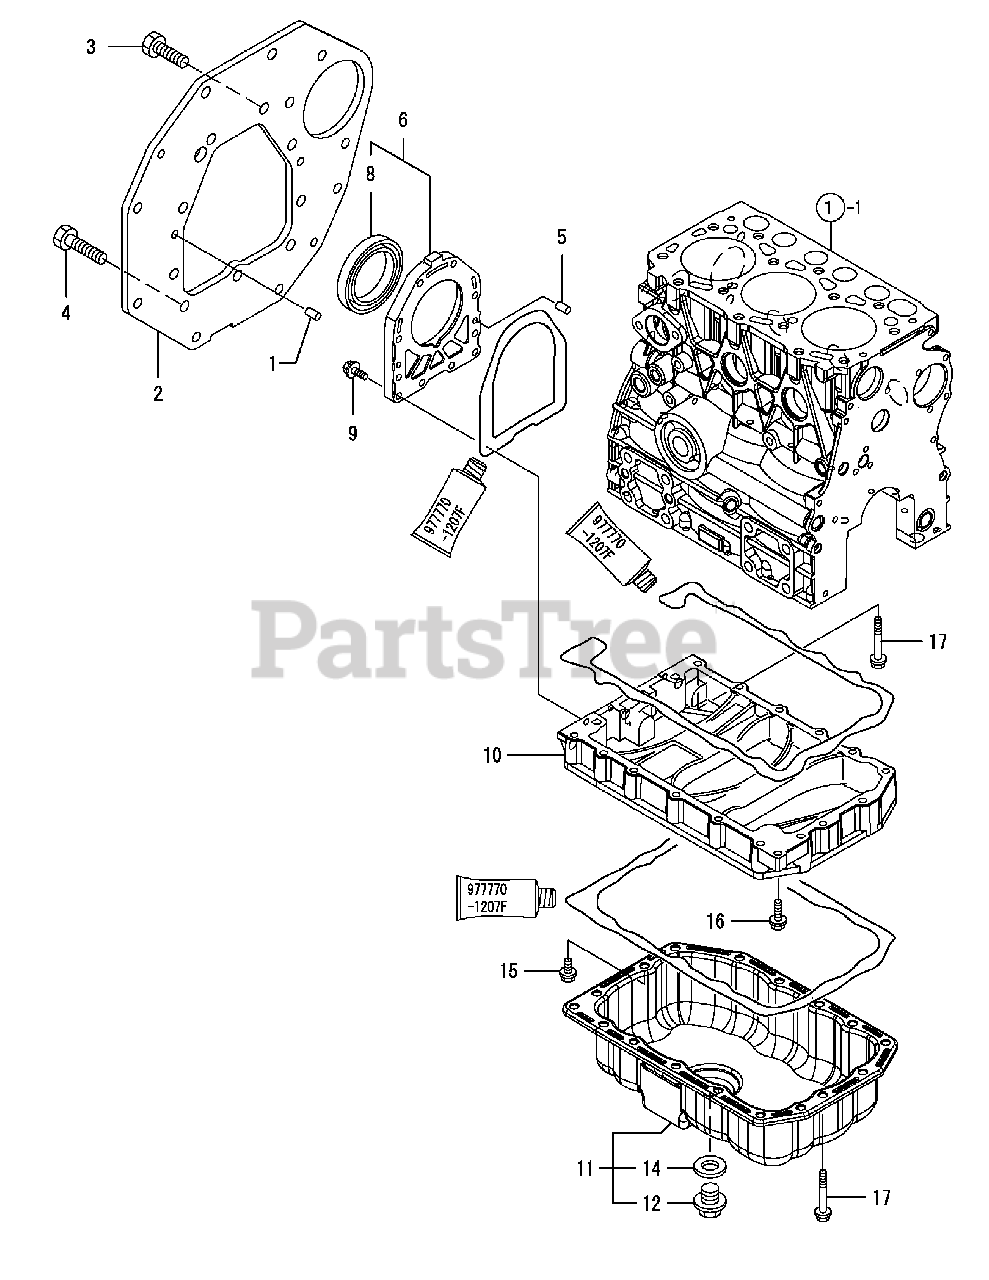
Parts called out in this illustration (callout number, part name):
1	Parallel Pin, 8 x 16
2	Flange, Mounting
3	Bolt, M10 x 20
4	Bolt, M10 x 25
5	Parallel Pin, 6 x 10
6	Case Assembly, Oil Seal
9	Bolt, M 6 x 22 Plated
10	Spacer, Oil Sump
11	Sump Assembly, Lub. Oil
14	Seal, Washer, 16S
15	Bolt, M 6 x 12 Plated
16	Bolt, M 6 x 25 Plated
17	Bolt, M 6 x 45 Plated
